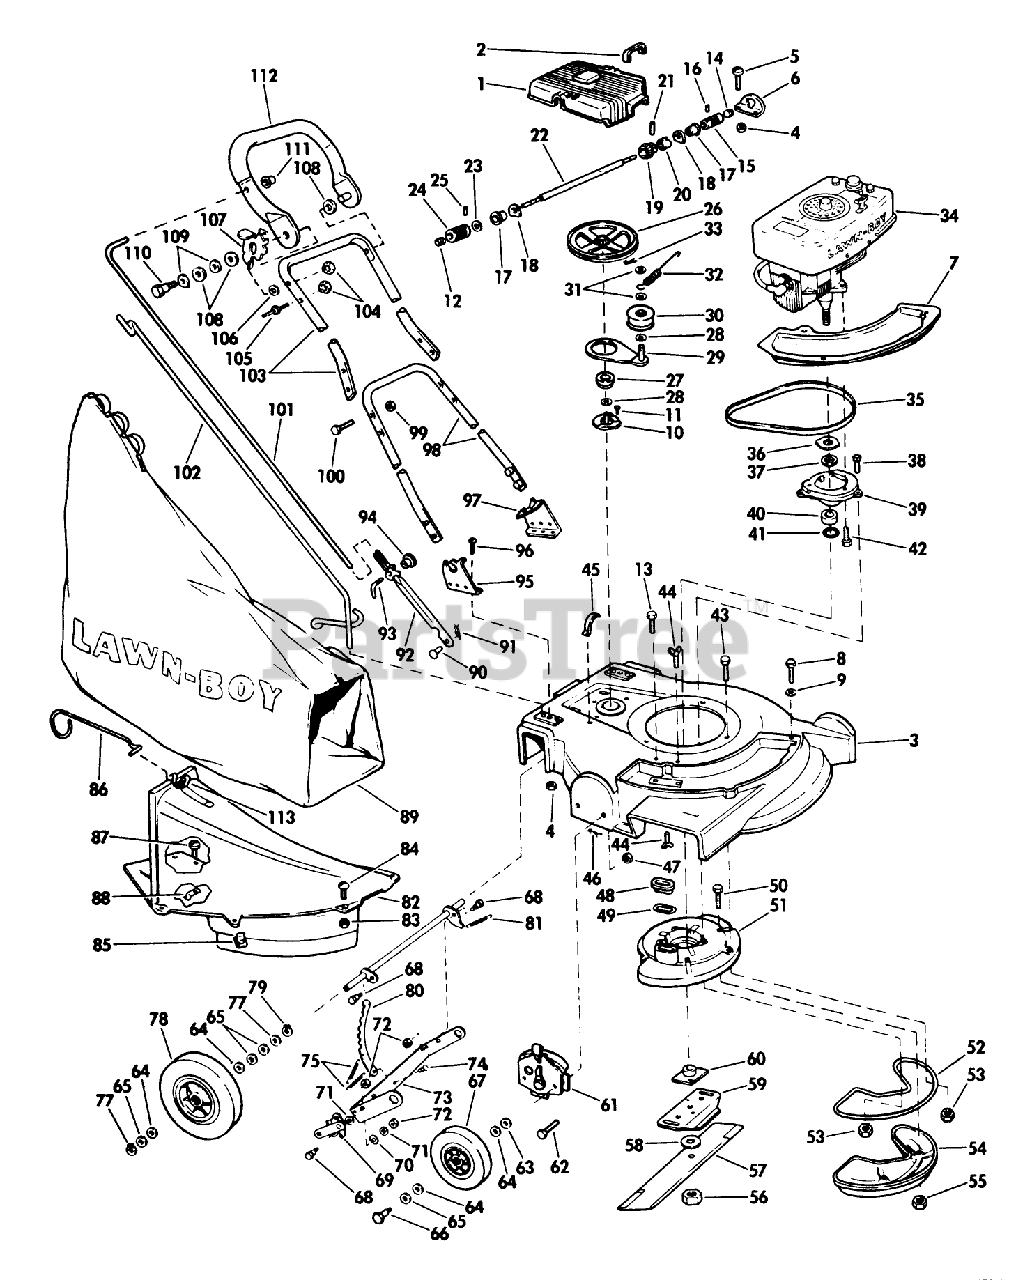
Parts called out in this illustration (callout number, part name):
5	SCREW
8	SCREW SEMS TRM HEX HD
14	GREASE PLUG
26	PULLEY&OILER FELT (13)
35	BELT
42	BOLT F
43	SCREW
47	NUT
48	SLEEVE
49	GASKET S
53	NUT
55	LOCKNUT E
56	NUT-BLADE
58	WASHER
60	PLATE AND COLLAR ASM
63	WASHER WROUGHT
64	WASHER
65	SPACER
66	BOLT WHEEL
67	WHEEL & TIRE KIT
68	BOLT RB&W
71	WASHER S
72	STOP NUT
77	RETAINING RING
79	WASHER
81	SPRING
82	Skirt Assembly
83	NUT S
85	SPEED NUT ARDEN
89	89802 LB WHOLE GOODS
96	SCREW S
100	SCREW
108	WASHER M
110	BOLT PIONEER
